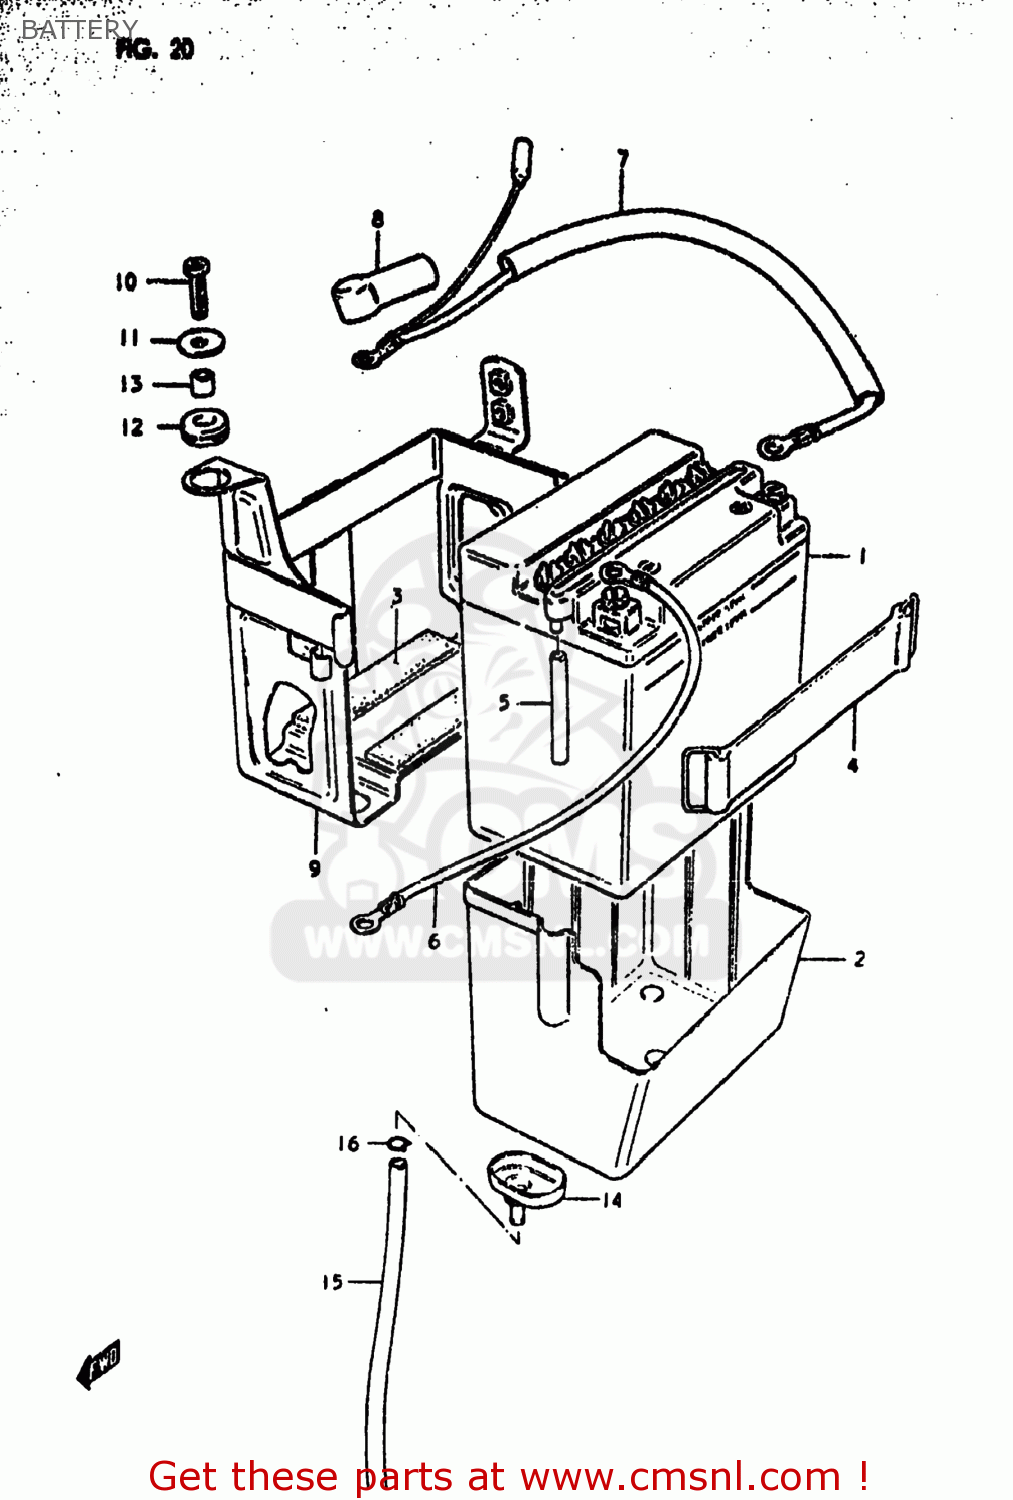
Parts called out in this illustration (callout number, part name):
1	BATTERY ASSY (12V)
2	CASE,BATTERY
3	PROTECTOR,20X9
4	BAND
5	HOSE, EXHAUST (L:45)
6	WIRE,STARTER MOTOR LEAD
7	WIRE,BATTERY PLUS
8	CAP,TERMINAL
9	HOLDER,BATTERY
10	BOLT(6X20)
11	WASHER
12	CUSHION
13	SPACER(6.1X9X7.5)
14	FUNNEL,BATTERY EXHAUST
15	HOSE,BATTERY EXHAUST
16	CLIP
